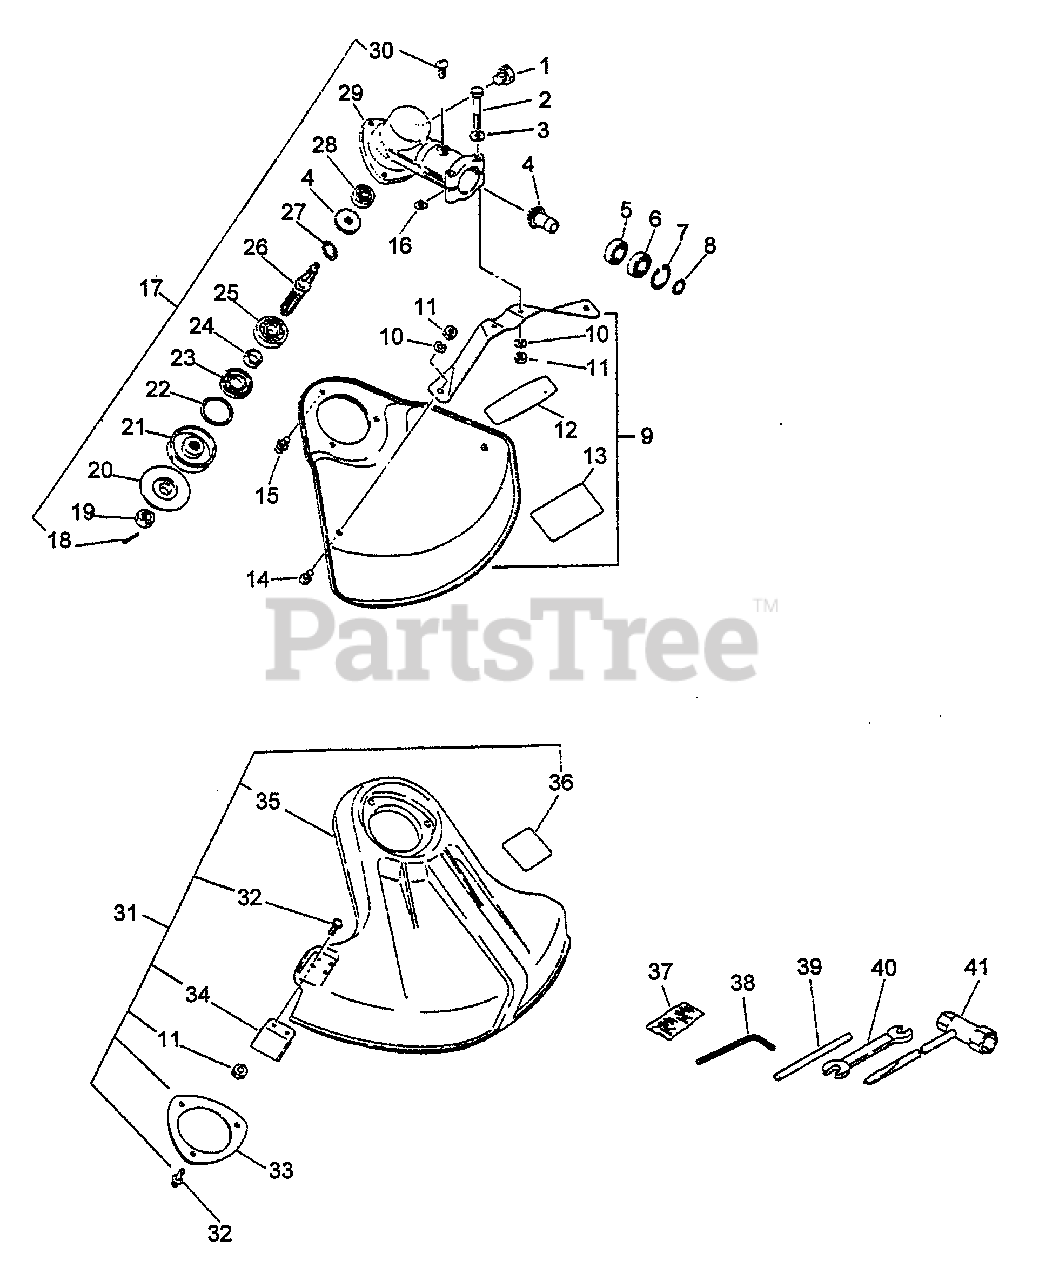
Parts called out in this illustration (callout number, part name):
1	BOLT 8×8 SP
2	BOLT 5×40
3	WASHER, FLAT 5.5×10×0.8
4	GEAR SET
5	BEARING, BALL 6001
6	BEARING, BALL 6001
7	RING, SNAP 28
8	RING, RETAINING - 12
9	SHIELD
10	WASHER, SPRING 5
11	NUT M5
12	LABEL, ECHO
13	LABEL, DANGER
14	SCREW 5×8
15	SCREW 5×10
17	GEAR CASE ASSY
18	PIN, COTTER 2×22
20	PLATE, ADAPTOR - LOWER
21	PLATE, ADAPTER - UPPER
22	RING, SNAP Ø32
23	SEAL, OIL 22
24	SPACER 11.8×15×9
25	BEARING, BALL - 6201 C3
26	SHAFT, GEAR
27	RING, SNAP Ø12
28	BEARING, BALL 6000
29	CASE, GEAR
30	SCREW 5×10
31	DEBRIS SHIELD ASSY
32	SCREW 5×16
33	PLATE, SHIELD Ø49.5 MM
34	CUTTER, LINE
35	SHIELD, DEBRIS
36	LABEL, CAUTION
37	PIN, COTTER 2×22 (PKG. OF 10)
38	WRENCH, ALLEN 4 MM
39	TOOL, LOCKING 5×120 MM
40	SPANNER 8×10
41	T-WRENCH 17x-19 L200
